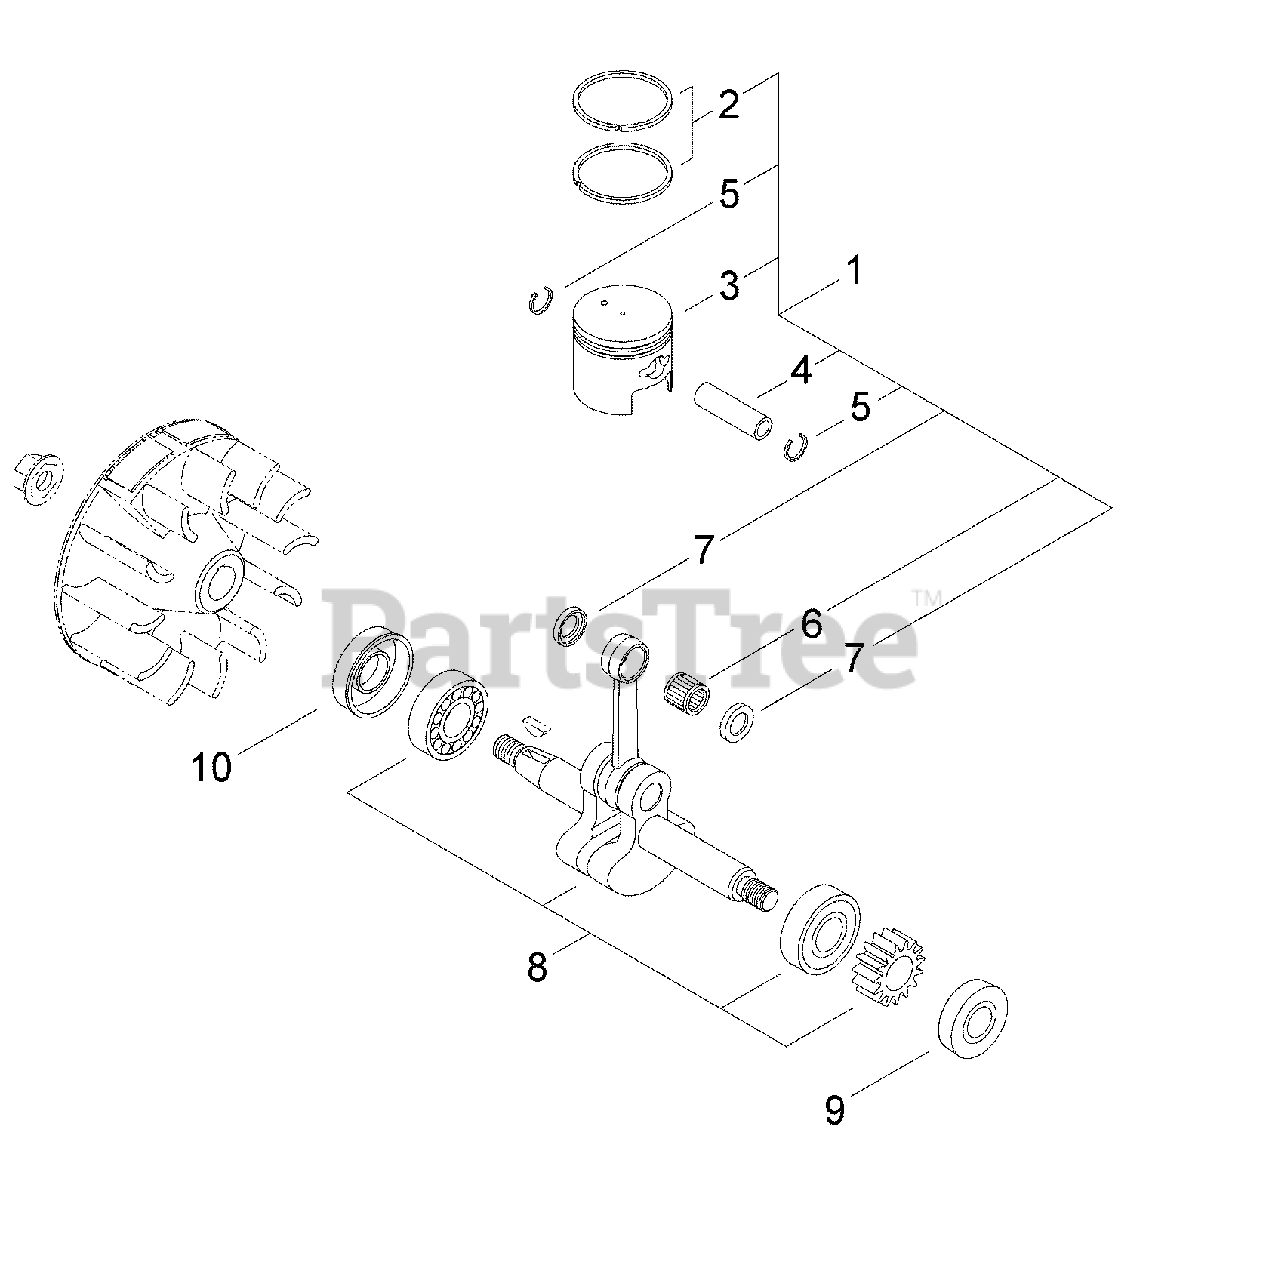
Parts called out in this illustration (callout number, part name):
1	PISTON KIT
2	RING, PISTON
3	PISTON
4	PIN, PISTON
5	RING, SNAP
6	BEARING, NEEDLE 9
7	WASHER, THRUST 9
8	CRANKSHAFT ASSY
9	SEAL, OIL 12
10	SEAL, OIL 12
